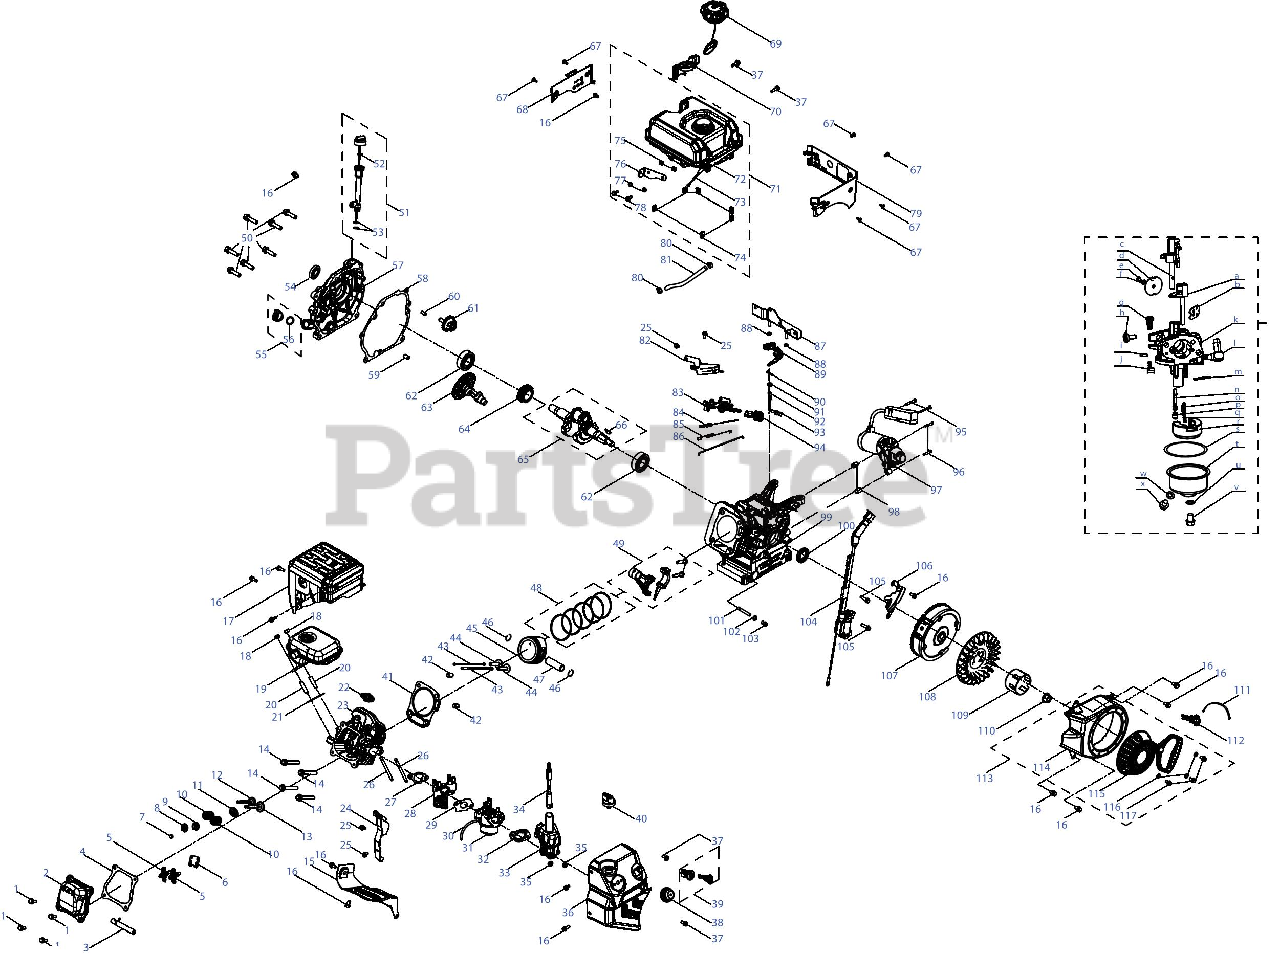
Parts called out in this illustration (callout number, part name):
1	Bolt, M6x16
2	Valve Cover
3	Breather Hose
4	Gasket, Valve Cover
5	Rocker Arm Assembly
6	Rocker Arm Base
7	Valve Adjust Cap, Exhaust
8	Valve Spring Seat
9	Valve Spring Seat
10	Valve Spring
11	Intake Valve Seal
12	Exhaust Valve
13	Intake Vavle
14	Bolt, M8x55
16	Bolt, M6x12
17	Muffler Guard
20	Stud, M8x34
21	Gasket, Muffler
22	Spark Plug
23	Cylinder Head
24	Snow Guard
25	Bolt, M6x12
26	Stud, M6x90
27	Gasket, Carburetor Insulator
29	Gasket, Carburetor
30	Fuel Hose,3.2x6.5x170
31	Carburetor
32	Gasket, Air Filter
33	Heater Box
34	Choke Linkage
36	Control Panel
37	Bolt, M6x18
39	Stop Switch
40	Choke Lever
41	Gasket, Cylinder Head
42	Pin, 10x16
43	Push Rod
47	Piston Pin
48	Piston Ring Set
49	Connecting Rod Assembly
50	Bolt, M8x32
51	Dipstick
52	O-Ring, 21x2.77
53	O-Ring, 15.2x1.5
54	Oil Seal, 25x41.25x6
56	O-Ring, 15.8x2.5
57	Crankcase Cover
58	Gasket, Crankcase
59	Pin, 9x14
60	Pin, 7x14
61	Governor Gear
62	Bearing, 6205
64	Drive Timing Gear
65	Crankshaft
66	Woodruff Key
67	Bolt, M5x14
68	Decorative Sheet, Right
70	Decorative Cover
71	Fuel Tank Assembly
72	Fuel Tank
73	Fuel Filter
74	Fuel Tank Mount Thread Tab
76	Fuel Tank Mount Tab
77	Washer, 6.5x1.5x12
78	Bolt, M6x20
79	Decorative Sheet, Left
80	Clamp
81	Fuel Hose, 6.3x12.5x162
82	Governor Shield
83	Governor Gear Bracket Assembly
84	Governor Spring
85	Idle Spring
86	Throttle Linkage
87	Fuel Tank Bracket
89	Governor Lever
90	Cotter Pin
91	Oil Seal, 6x11x4
92	O-Ring, 5.2x1.9
93	Governor Gear Shaft
94	Throttle Lever Knob
95	Screw, M4x48
96	Bolt, M6x32
97	Electric Starter
98	Pin, 8x8
100	Oil Seal, 25x41.25x6
101	Oil Drain Pipe
102	Washer, 10x1.5x16
103	Earth Bolt
104	Ignition Module
105	Bolt, M6x25
106	Lower Shield
107	Flywheel
108	Cooling Fan
109	Starter Cup
110	Nut, M14x1.5
111	Tape, L=150mm
112	Stop Switch Key
113	Recoil Starter
114	Blower Housing
115	Recoil Starter
116	Washer, 6
117	Bolt, M6x10
